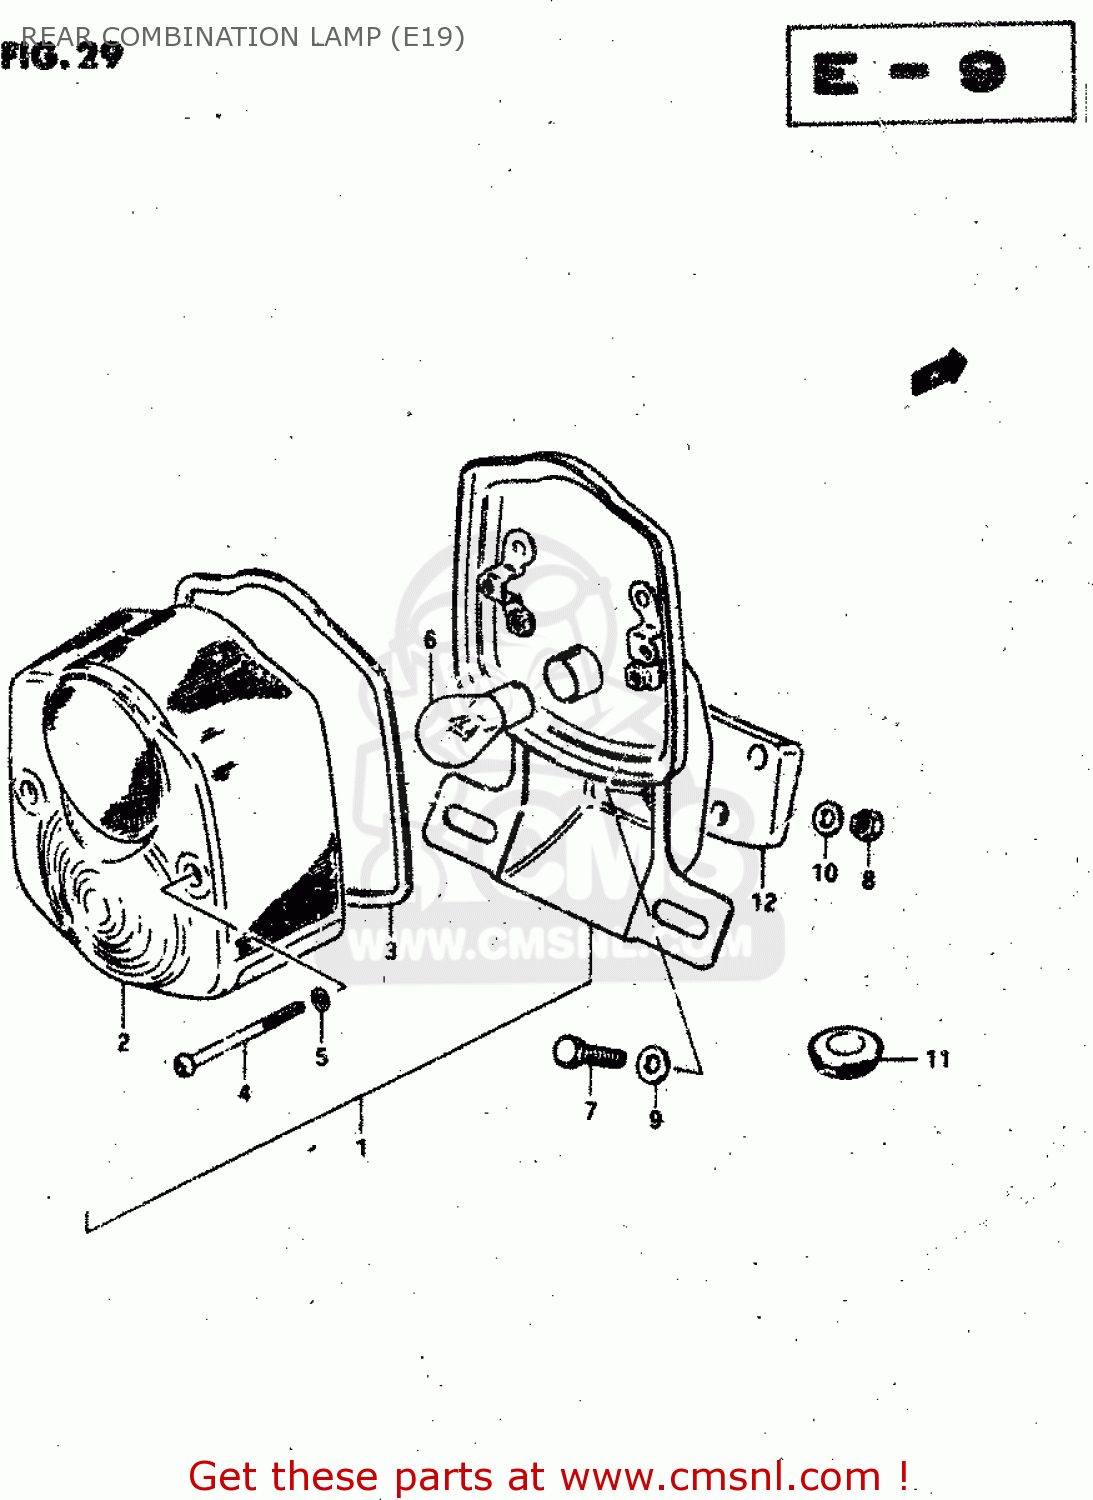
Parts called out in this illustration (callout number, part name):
1	LAMP ASSY, TAIL
2	LENS,RR COMBI
3	GASKET (NAS)
4	SCREW
5	GASKET (NAS)
6	BULB (6V,21/5W)
7	BOLT
8	NUT
9	WASHER
10	WASHER (6.5X20X1.2)
11	GROMMET
12	CUSHION
